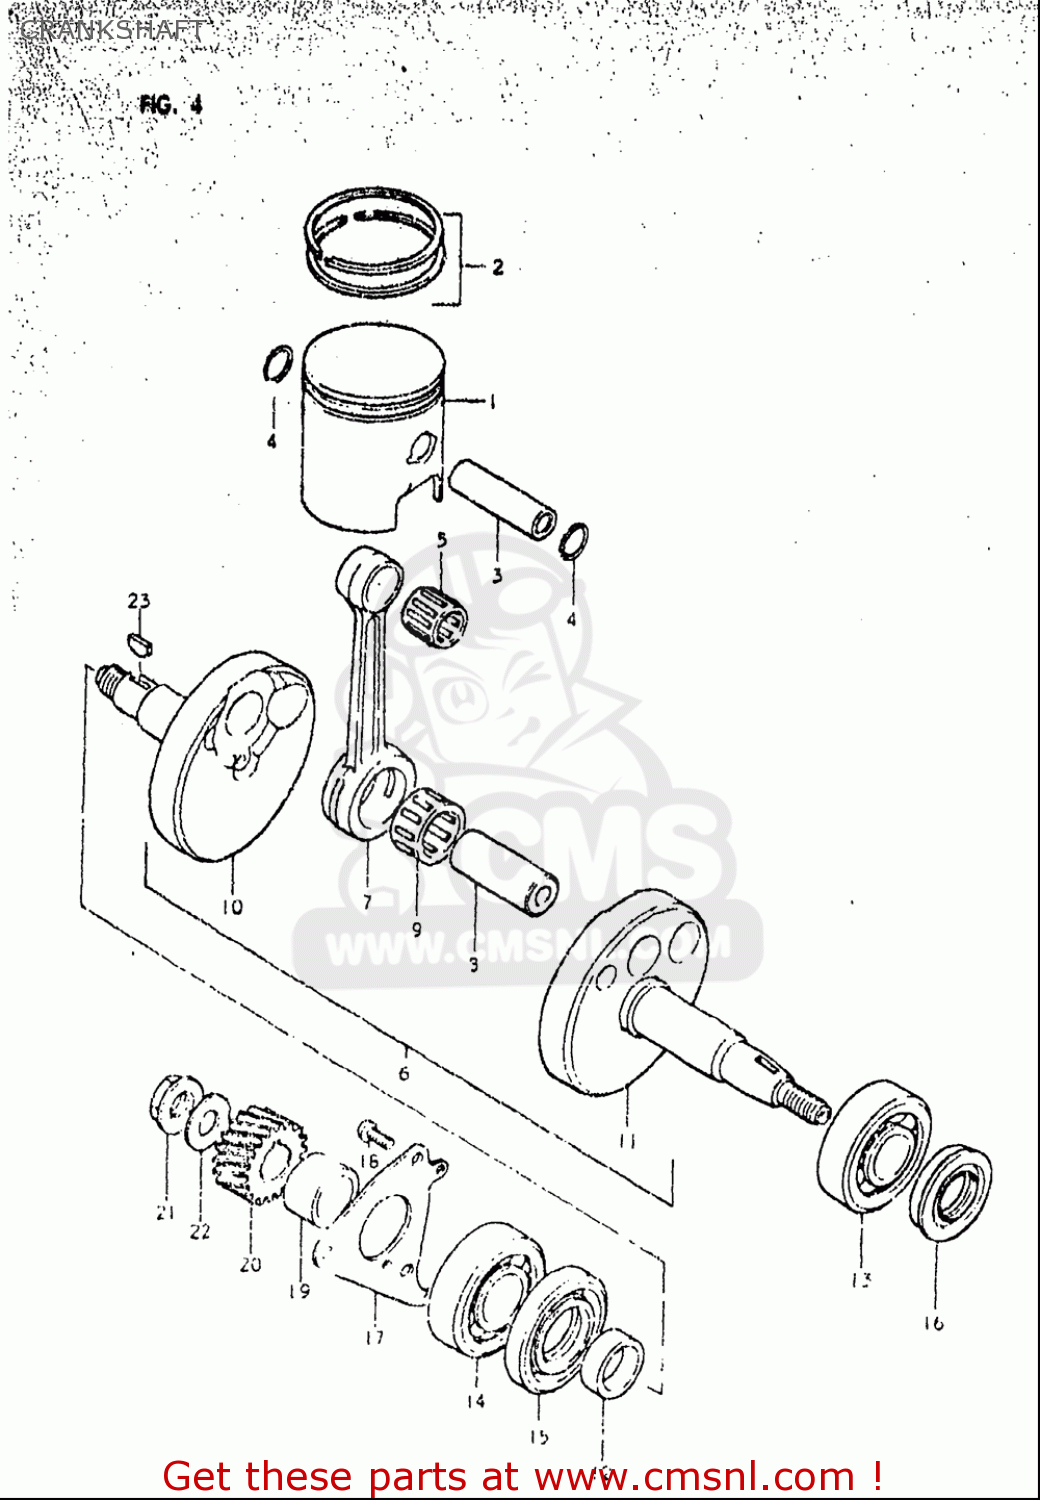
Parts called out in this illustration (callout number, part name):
1	PISTON(41.00MM)
2	RING SET,PISTON
3	PIN,PISTON
4	RING,SNAP
5	BEARING(12X16X16)
7	ROD,CONNECTING
8	PIN,CRANK
9	BEARING(16X22X11.8)
12	SPACER(20X26X9)
13	BEARING(20X47X14)
14	BEARING(20X47X14)
15	SEAL,OIL(26X47X7.3)
16	SEAL,OIL(19.6X37X8)
18	SCREW
19	SPACER(20X26X14)
20	GEAR,PRIMARY DRIVE NO.19
21	NUT
22	WASHER
23	KEY
